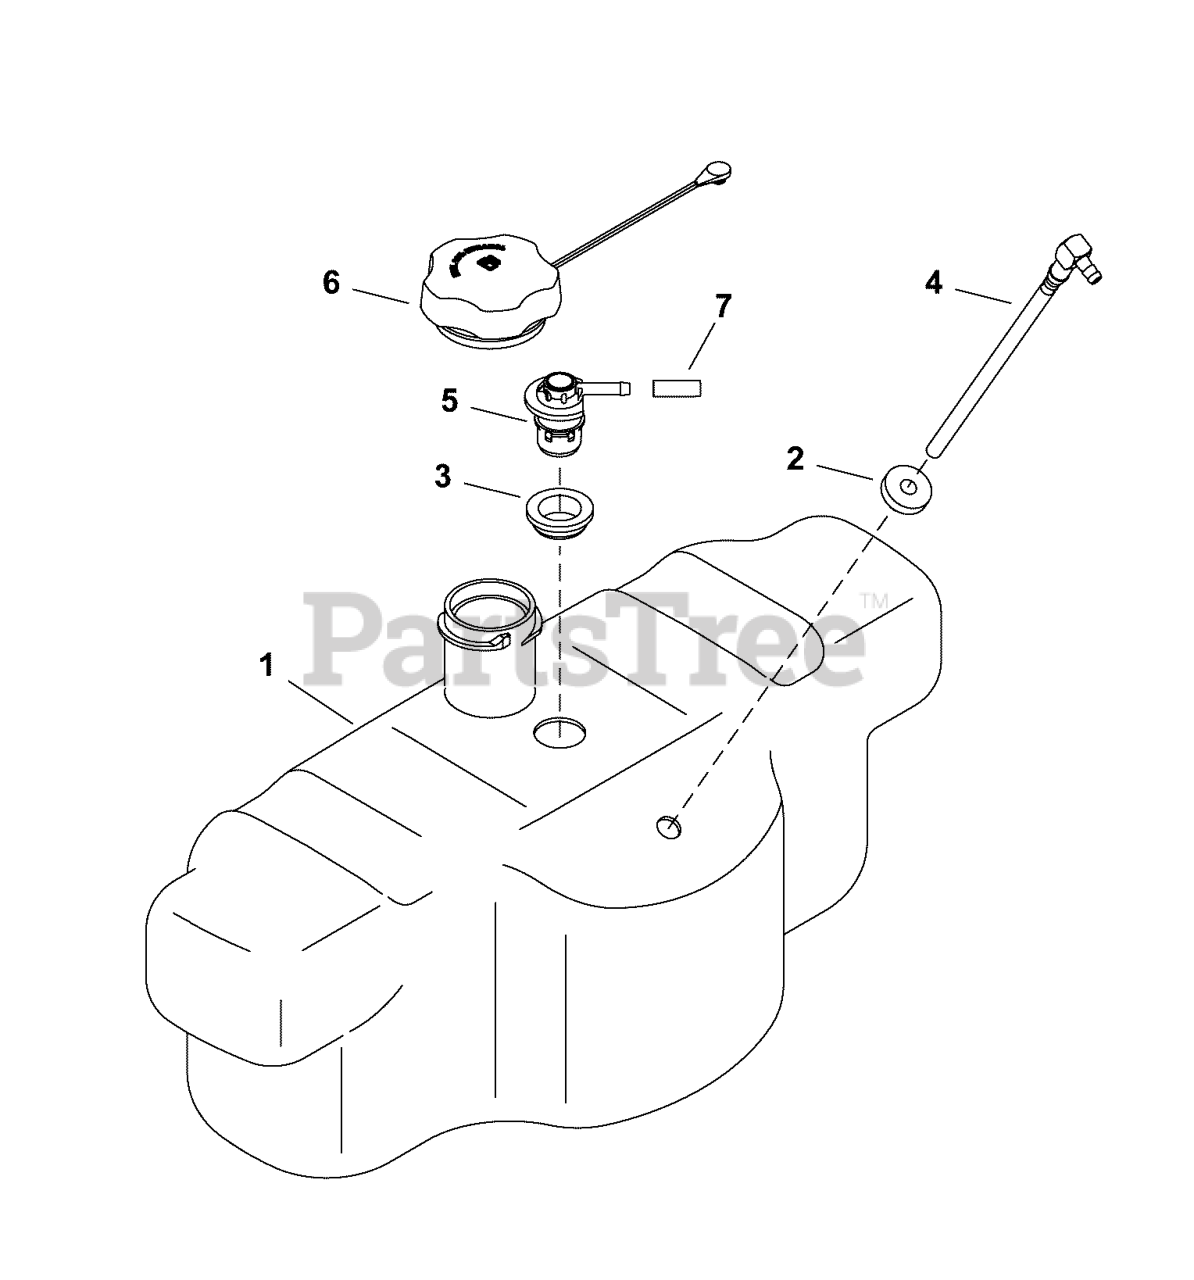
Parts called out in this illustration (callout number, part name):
1	TANK, Fuel
2	BUSHING, Fuel Tank
3	GROMMET, Rubber
4	FITTING, Fuel Pickup
5	VALVE, Rollover
6	CAP, Fuel
7	HOSE, Vent
